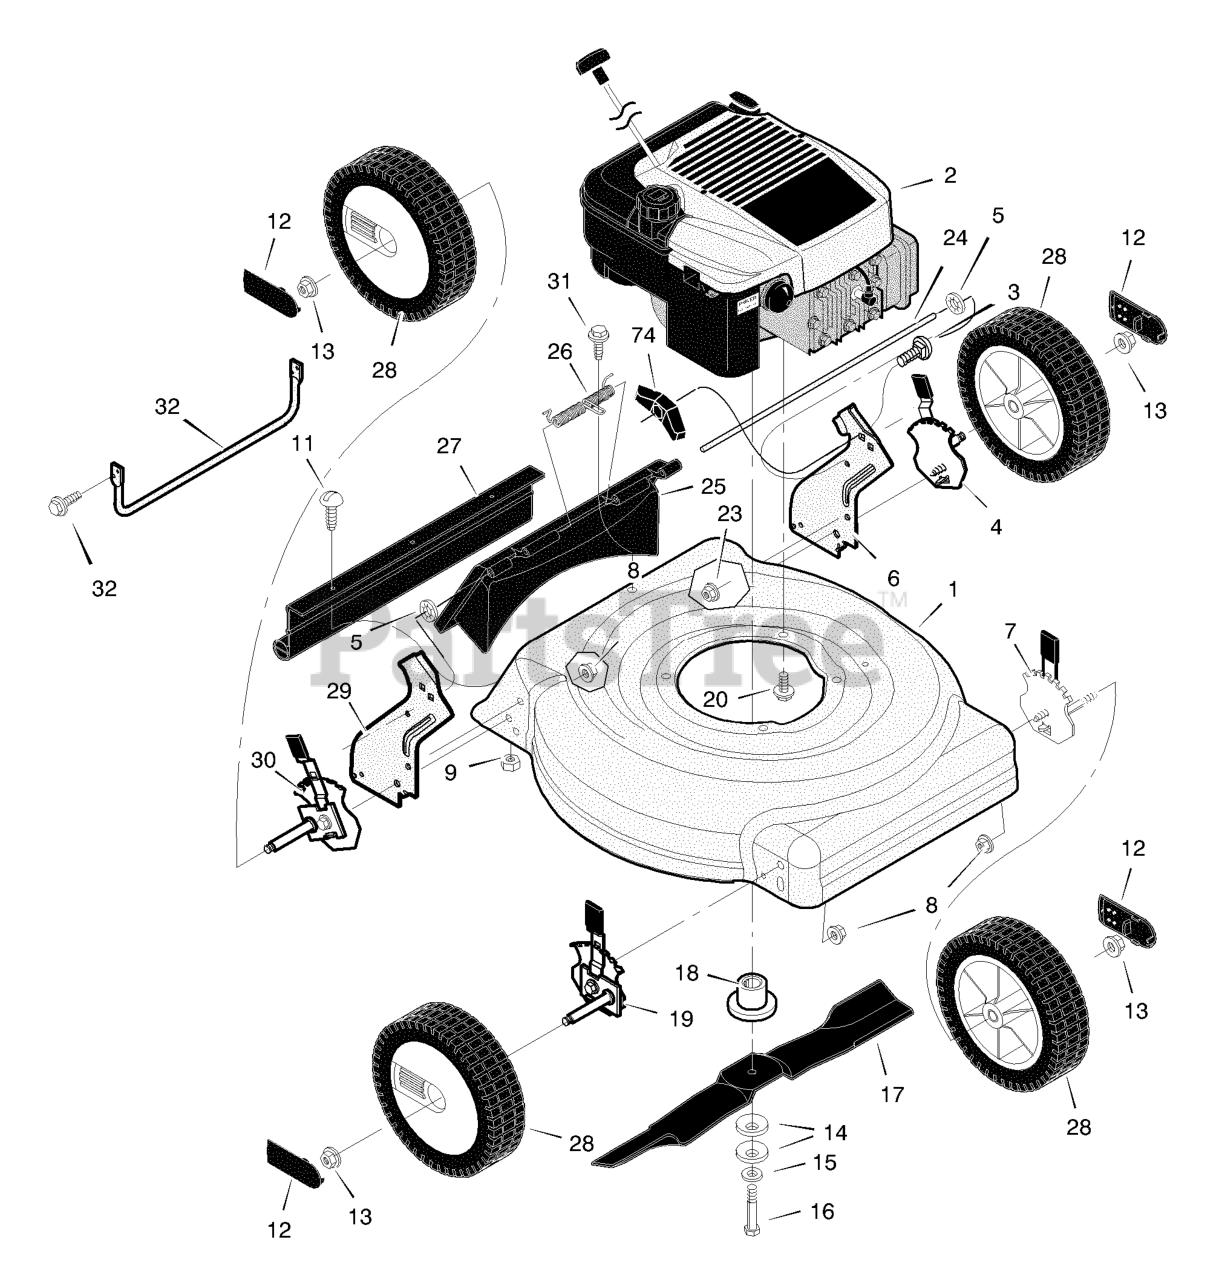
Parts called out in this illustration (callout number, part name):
1	Housing
2	Engine
3	Bolt, Carriage
4	Adjuster, Left Rear Height
5	Push Retainer
6	Bracket, Left Handle
7	Adjuster, Left Front Height
8	Nut, Flange
12	Hub Cap
13	Nut, Flange
14	Washer, Belleville
18	Adapter, Blade
19	Adjuster, Right Front Height
20	Bolt, Engine
23	Nut, Flange
24	Rod, Pivot
25	Door, Rear
27	Guard, Rear
29	Bracket, Right Handle
30	Adjuster, Right Rear Height
32	Guard, Rear
33	Screw
